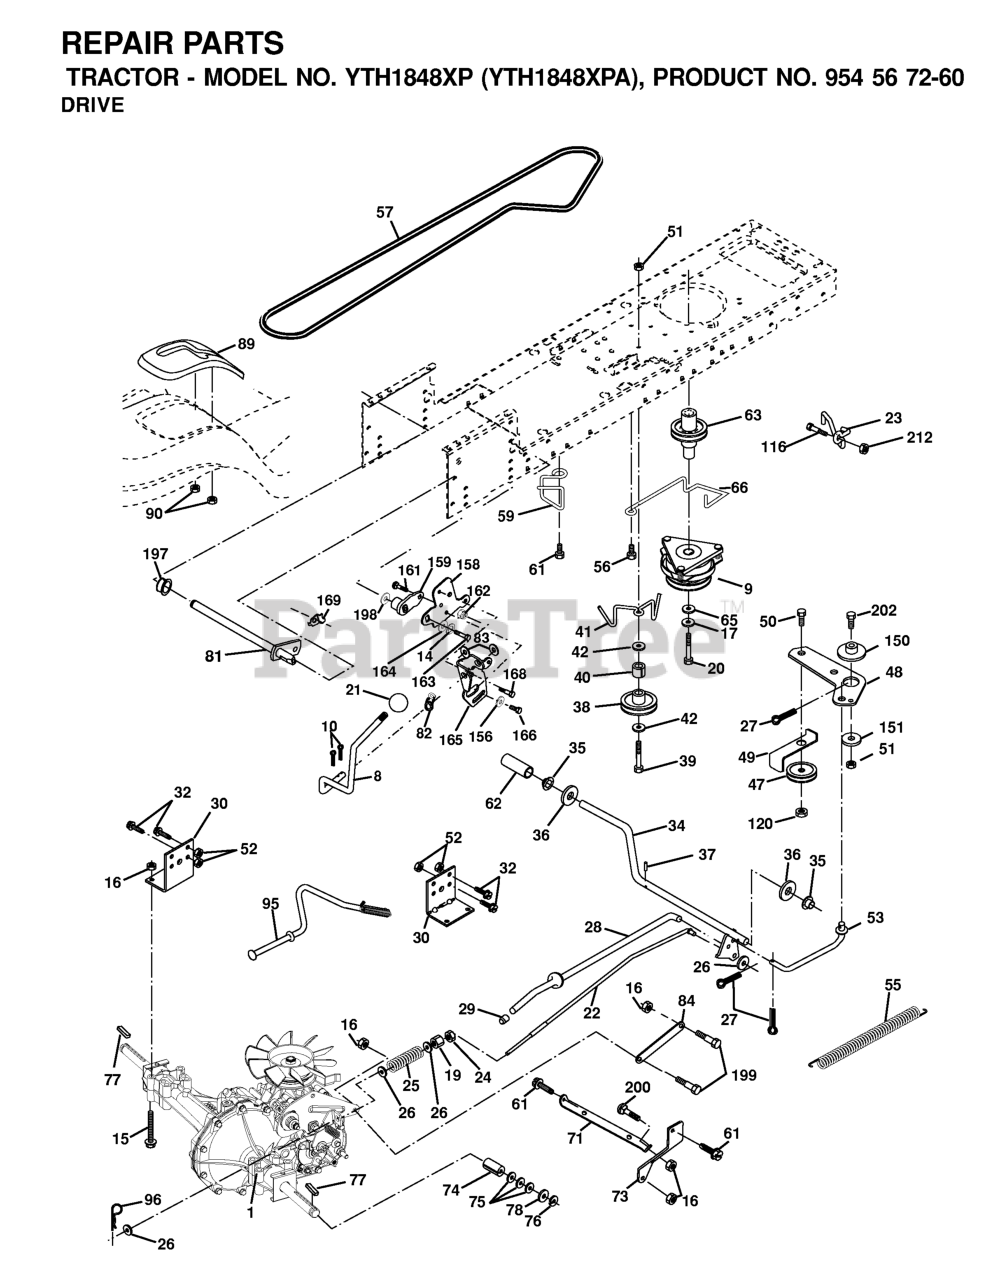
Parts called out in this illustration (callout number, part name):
8	ROD SHIFT FENDER ADJUST STLT
9	CLUTCH, ELECTRIC
10	PIN COTTER
14	LOCKWASHER
15	BOLT HEX 5/16-18 GR 5
16	NUT.71038.31-18.HEX.NYLOCK
19	NUT
20	BOLT HEX 7/16-20X4-1/4"
21	KNOB.DELUXE.(PISTOL.GRIP).BLAC
22	ROD BRAKE HYDRO
23	BRKT ASM MTNG
24	NUT
25	SPRING ROD LT
26	WASHER
27	COTTER PIN
28	ROD, PARKING BRAKE
29	PLUNGER CAP
30	BRKT, TRNSXLE MNT 20"
32	BOLT
34	SHAFT, FOOT PEDAL
35	BEARING.NYLON
36	WASHER LT
37	DRIVE PIN
38	PULLEY.FLAT
39	BOLT
40	SPACER, SPLIT
41	KEEPER, BELT IDLER
42	WASHER
47	IDLER PULLEY
48	BELLCRANK, CLUTCH
49	RETAIN BELT
50	BOLT
53	LINK, CLUTCH LT
55	SPRING, RETURN LT
56	SCREW THDROL 3/8-16 X 1-1/2
57	DRIVE BELT, LTH & YTH TRACTORS
59	KEEPER, BELT CENTER
61	SCREW 3/8-16X3/4
62	PEDAL COVER T
63	PULLEY, ELEC CLUTCH
65	LOCKWASHER
66	KEEPER BELT ENGINE
71	STRAP TORQUE LH HYDRO
73	STRAP TORQUE RH HYDRO
74	SPACER AXLE
77	SQUARE KEY
81	SHAFT ASM CROSS TAPERED
82	SHIFT SPRING
83	WASHER
84	LINK TRANSAXLE
89	SHIFT CONSOLE
90	NUT.PUSH.3/16
95	CONTROL ASM. BYPASS HYDRO
96	RETAINER M
116	BOLT D
120	NUT LOCK FLG 3/8-16 UNC
150	SPACER, RETAINER
151	WASHER 12/32X2X10GA
156	WASHER.SRRTD.5/16
158	BRACKET
159	HUB
161	BOLT
162	NUT.CROWNLOCK.1/4
163	BOLT
164	Washer 5/8 x .281 x 10 Ga.
165	RP BRACKET
168	BOLT.SHOULDER.5/16-18X
169	PLATE.FASTENING.CROSS.SHAFT
197	NYLINER SNAP 5/8" ID
198	WASHER.NYL.7/8IDX.105"HYD CR
199	BOLT SHOULDER 5/16-18 UNC
200	BOLT
202	BOLT.3/8-16X1.50
212	NUT
